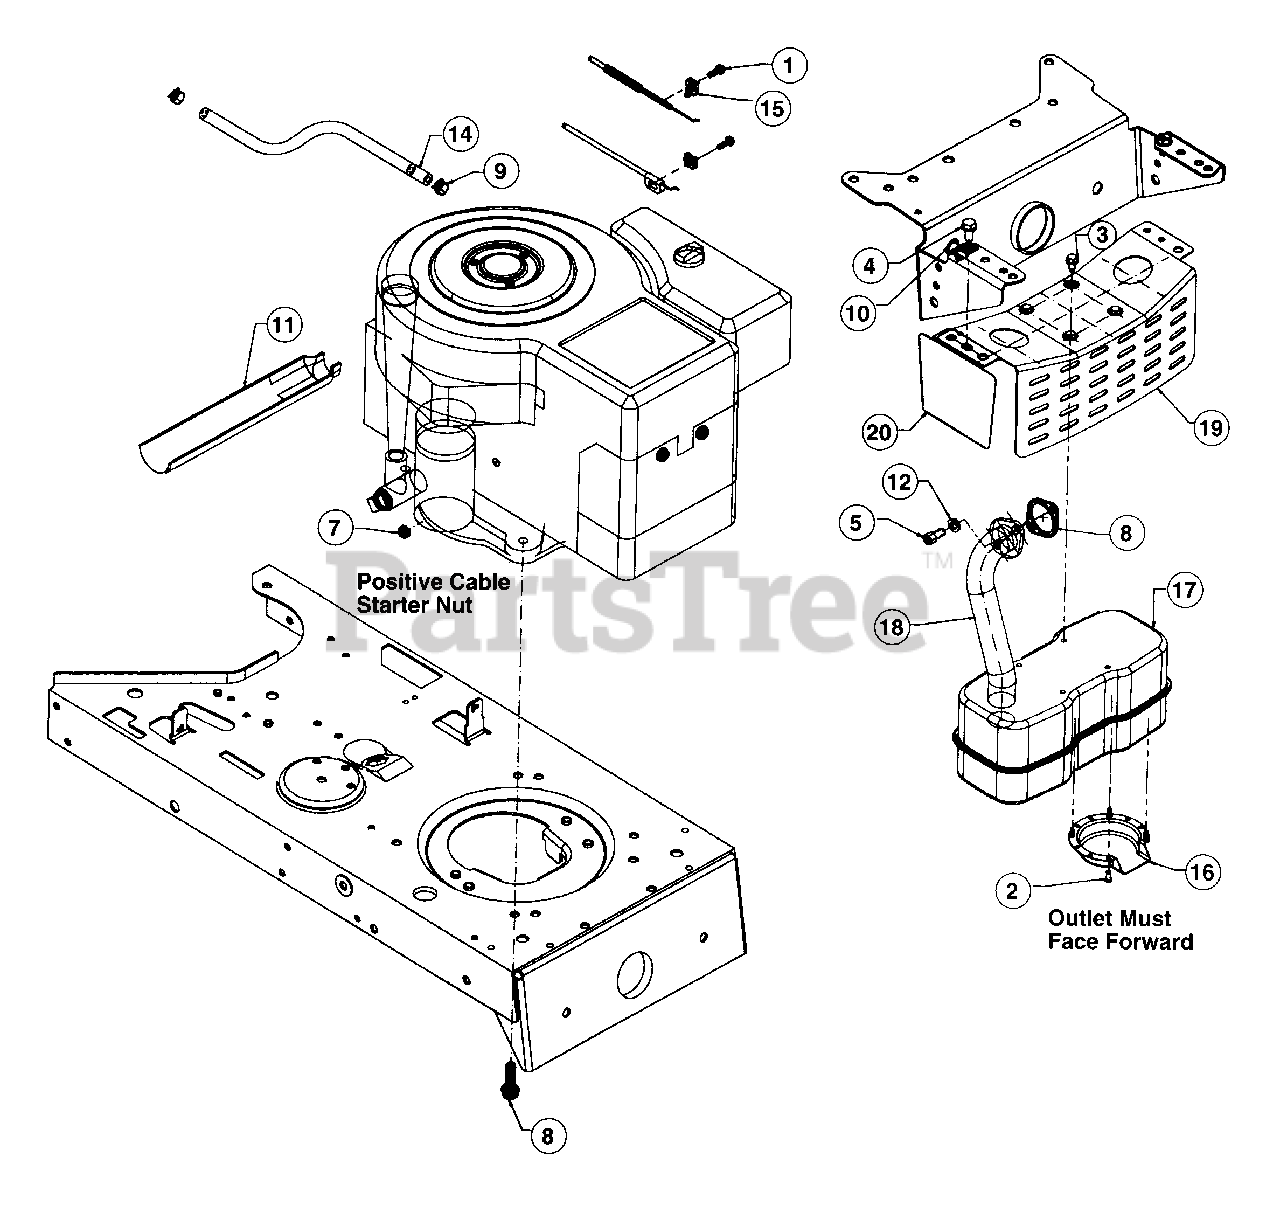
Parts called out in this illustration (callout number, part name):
1	Hex Wash. Scr. #10-32 x .62" Lg.
2	Hex Tap Scr. #8-32 x .38" Lg.
3	Hex Wash. TT-Tap Scr. 1/4-20 x .5" Lg.
4	Hex Wash. TT-Tap Scr. 5/16-18 x .62" Lg.
5	Socket Head Scr. 5/16-18 x .62" Lg.
7	Hex Sems Scr. 1/4-20 Thd.
8	Gasket
11	Oil Drain Sleeve
12	Lock Washer 5/16" I.D.
14	Fuel Line 12" Lg.
15	Casing Clamp
16	Muffler Deflector
17	Muffler
18	Exhaust Pipe
19	Muffler Brkt.
20	Shield Brkt.
